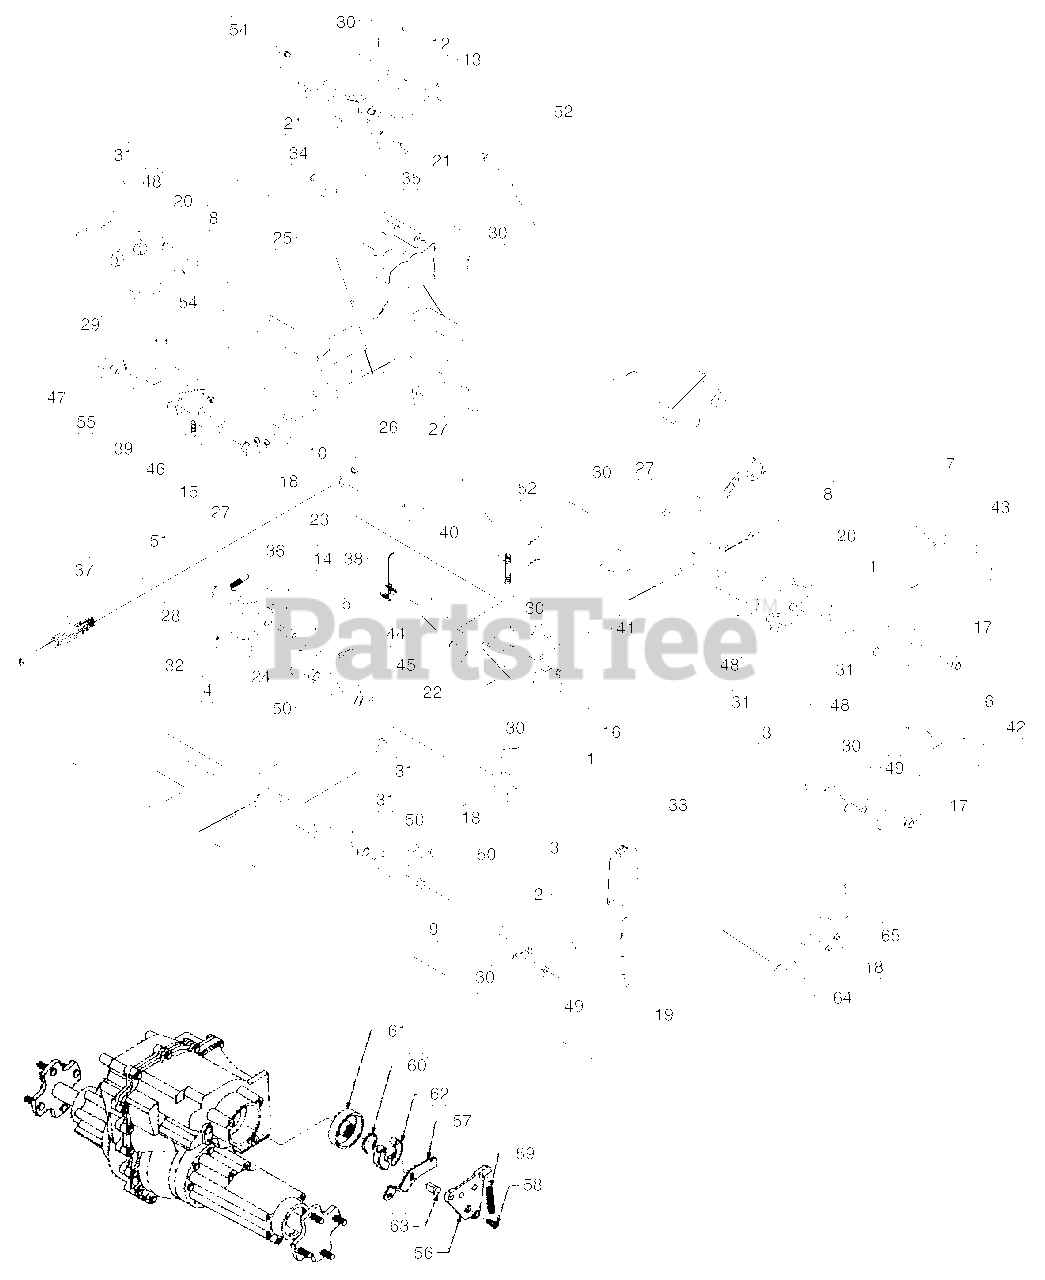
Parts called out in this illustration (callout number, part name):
1	Shaft Assy, Brake
4	Cam Assy, Control
5	Plate Assy, Disengagement
6	Pedal, Forward
7	Pedal, Brake
8	Plate, Bearing Mounting
10	Bracket, Cruise
11	Plate, Rod Adjustment
15	Screw, Hex Cap, 1/4-20 x 1.25
16	Screw, Hex Wshr Tap 1/4-20 x .5
17	Screw, Hex Wshr Tap 3/8-16 x .75
18	Screw, Hex Wshr Tap 1/4-20 x .75
19	Screw, Truss Mach, #12 x 1.5
20	Screw, Hex Cap, 3/8-16 x .75 GR5
21	Screw, Phil Hd Pan, #10-24 x .75
22	Pin, Clevis, 3/8 x 1.62
23	Ferrule, Adjustment, 1/4-20 Thrd
24	Stud, Actuator
25	Pin, Clevis, .25 x 2.38 Lg
26	Nut, Hex Sems, 1/4-20
27	Nut, Hex Flange Lock, 3/8-16
28	Nut, Hex Flange Lock, 5/16-18
29	Nut, Hex Flange Lock, 1/4-20
30	Pin, Int Cotter, 5/16 Dia x 1.12 Lg
31	Pin, Int Cotter, 3/8 Dia x 1.62
32	Pin, Spiral Spring, 1/4 x 1.5
33	Pedal, Reverse
34	Knob, Cruise
35	Knob, Brake Lock
36	Spring, Extension, .38 OD x 2.1
37	Spring, Extension
38	Spring, Torsion
39	Spring, Ext, .437 OD x 1.32
40	Spring, Compression, .50 x 2.23
41	Spring, Switch Actuator
42	Pad, Forward Foot Control
43	Pad, Brake Foot
44	Washer, Wave, .625 x .885 x .015
45	Washer, Flat, .635 x 1.0 x .020
46	Washer, Flat, 1/4 x .63 x .051
47	Shoulder Bolt, .50 OD x .840
48	Bearing, Hex Flange Split
49	Bearing, Flange, .375 x .58 x .25
50	Bearing, Flange, .626 x .93 x .344
51	Rod, Brake
52	Rod, Parking Brake
54	Rod, Cruise
55	Latch, Cruise
56	Plate, Brake
57	Arm, Brake
58	Screw, Low Hd Cap, 3/8-16 x .75
59	Spring, Compression
60	Spring, Brake
61	Drum, Brake
62	Shoe, Brake
63	Actuator, Brake Shoe
64	Rod, Rear Connecting
65	Rod, Front Connecting
